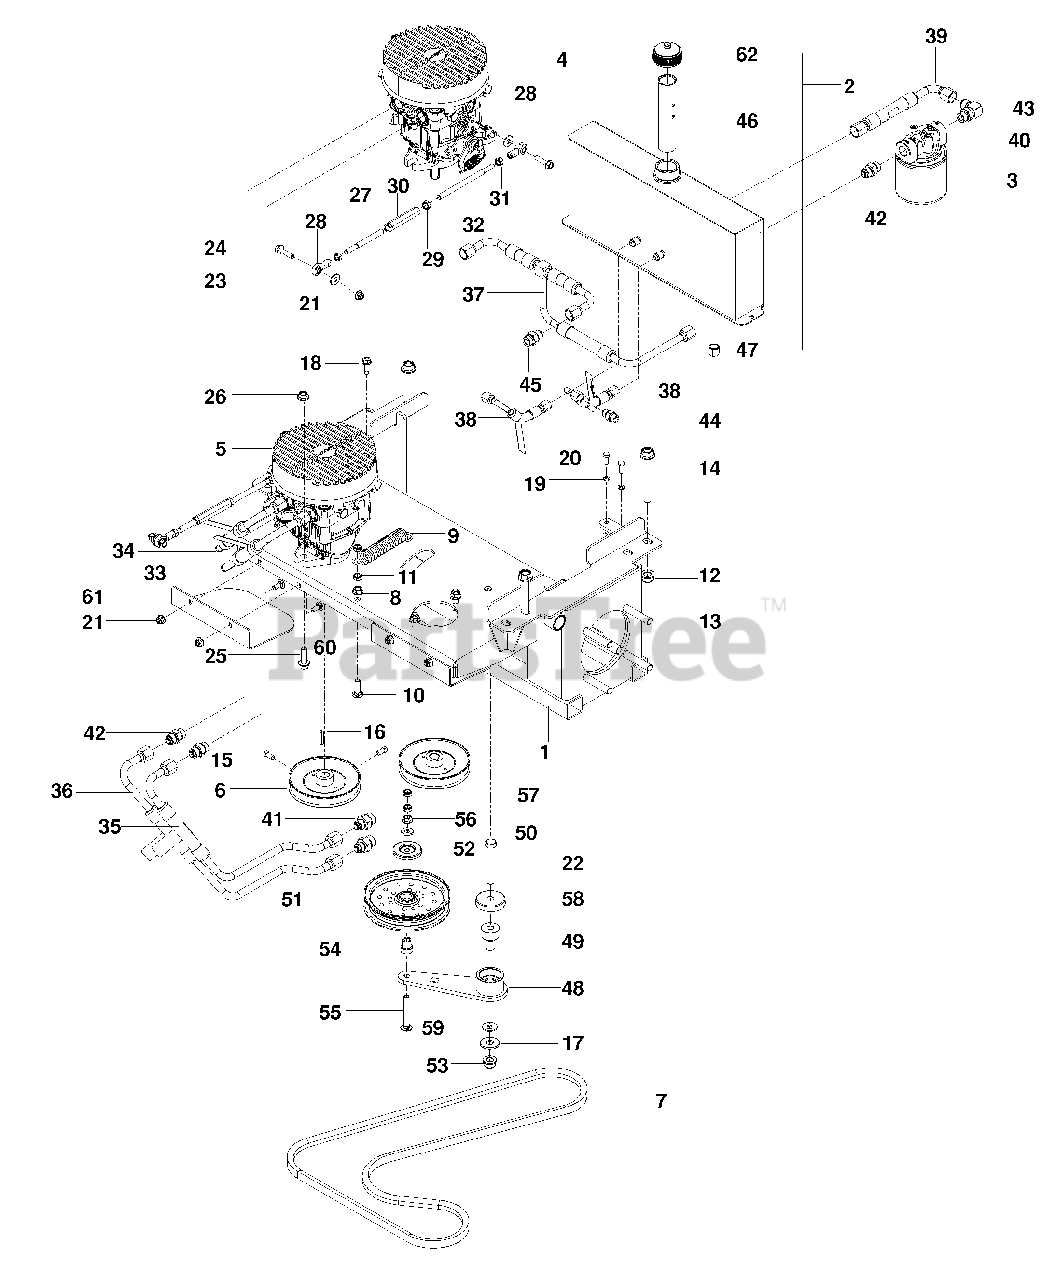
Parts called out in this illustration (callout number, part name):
1	Frame, Sub
2	Bolt 7/16-20 X 1 1/2 Hex Nyl
3	Filter, 25 Micron
4	Pump, 12Cc Rt
5	Pump, 12Cc Lt
6	Pulley, Pump, 15Mm
8	Nut 3/8-16 Hex Whizlk
9	Spring, Pump
10	Bolt 3/8-16 X 1 1/4 Rd Hd
11	Nut 3/8-16 Hex Jam Nyloc
12	Nut 1/2-13 Hex Flg Nyloc
13	Bolt 1/2-13 X 2 3/4 Hex Nyloc
14	Bolt 1/2-13 X 4 Hex Flg
15	Screw 5/16-18 X 5/8 Set
16	Key, Metric
17	Washer 1/2 Flat
18	Bolt 5/16-18 X 1 Thd Frm
19	Washer 1/4 Split Lock
20	Bolt 1/4-20 X 5/8 Hex Nyloc
21	Nut 5/16-18 Hex Flg Nyloc
22	Bolt 1/2-13 X 3 1/4 Hex Nyloc
23	Washer 5/16 Std Flt
24	Screw 5/16-18 X 1 1/4 Tpblt
25	Screw 3/8-16 X 1 1/4 Hex Flg
26	Nut 3/8-16 Hex Flg Nyloc
27	Linkage, Control, Ft
28	Ball End, Rt
29	Nut 3/8-24 Hex Jam
30	Turnbuckle 3/8
31	Nut 5/16-24 Hex
32	Linkage, Control, Rr
33	Line, Hydraulic, Rt-A
34	Line, Hydraulic, Rt-B
35	Line, Hydraulic, Lt-A
36	Line, Hydraulic, Lt-B
37	Line, Hydraulic, Charge
38	Line, Hydraulic, Case
39	Line, Hydraulic, Suction
40	Filter Head
41	Straight Connector
42	Straight Connector
43	Elbow 90O Adj
45	Straight Connector
46	Tube, Anti-Splash
48	Arm, Idler, W/ Bearings
49	Pivot, Bearing
50	Washer 3/8 Thick
51	Idler Pulley
52	Shield, Dust
53	Nut 1/2-13 Hex Flg Nyloc
54	Pivot, Idler
55	Bolt 3/8-16 X 2 3/4 Rd Hd
56	Nut 3/8-16 Hex Whizlk
57	Nut 3/8-16 Hex Jam Nyloc
58	Shield, Dust
59	Washer 1/2" Belleville
60	Bolt 5/16-18 X 3/4 Rd Hd
61	Shield, Pulley
62	Cap, Hydraulic
